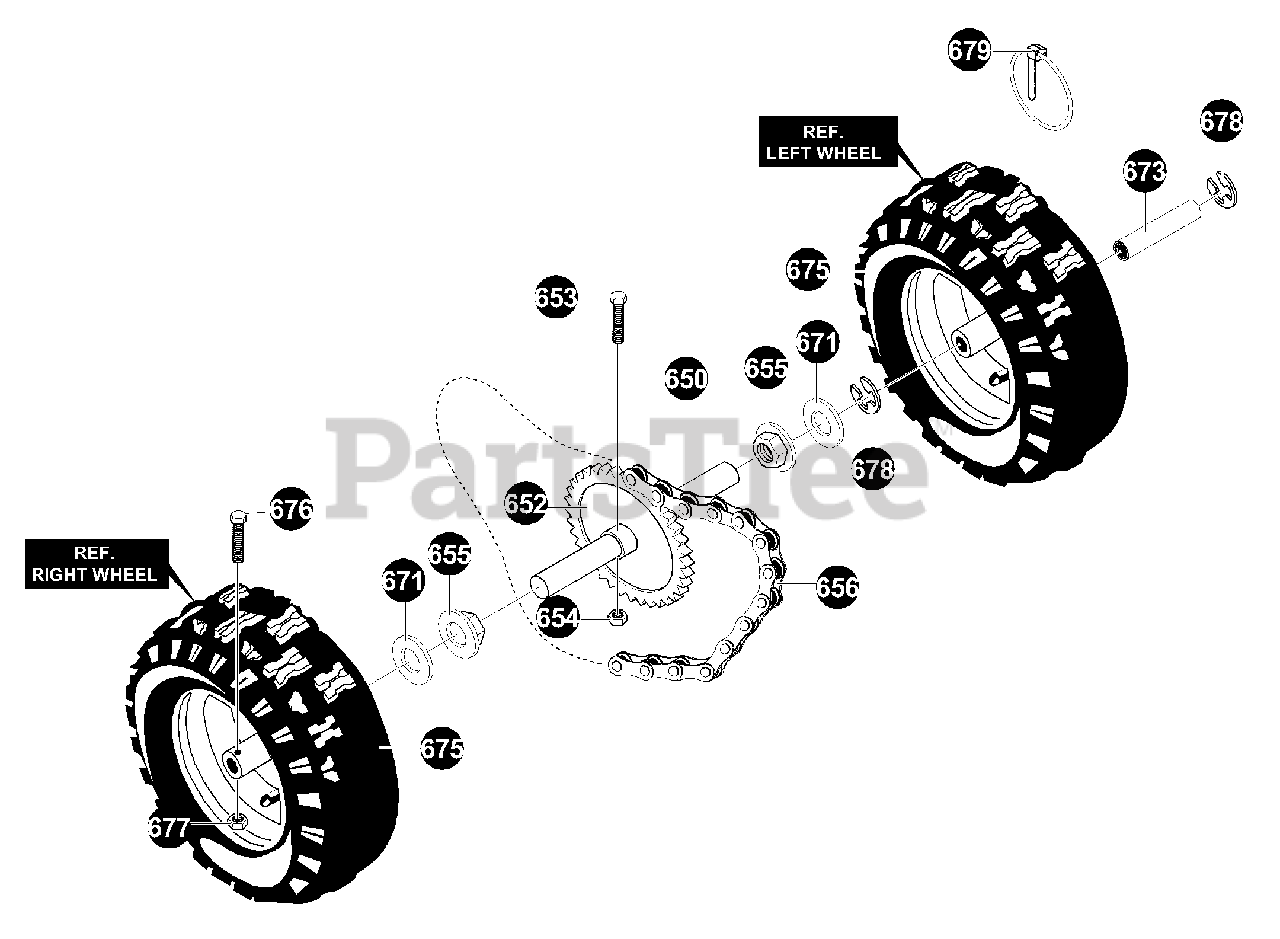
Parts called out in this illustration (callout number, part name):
650	SHAFT, AXLE WHEEL/MID
652	SPROCKET & HUB ASSY
653	SCREW 1/4-20X2.25
654	NUT, 1/4-20 REGHEXCTRLK
655	BEARING, FLANGE
656	CHAIN, ROLLER #42 X 40P
671	FLATWASHER .765X1.12X.06
673	BUSHING, WHEEL 4"LG
675	TIRE & RIM 13X5.0X6
676	SCREW, SHR 1/4-20X1.75
677	NUT 1/4-20 REGHEXCTRLK
678	RING, RETAINING
